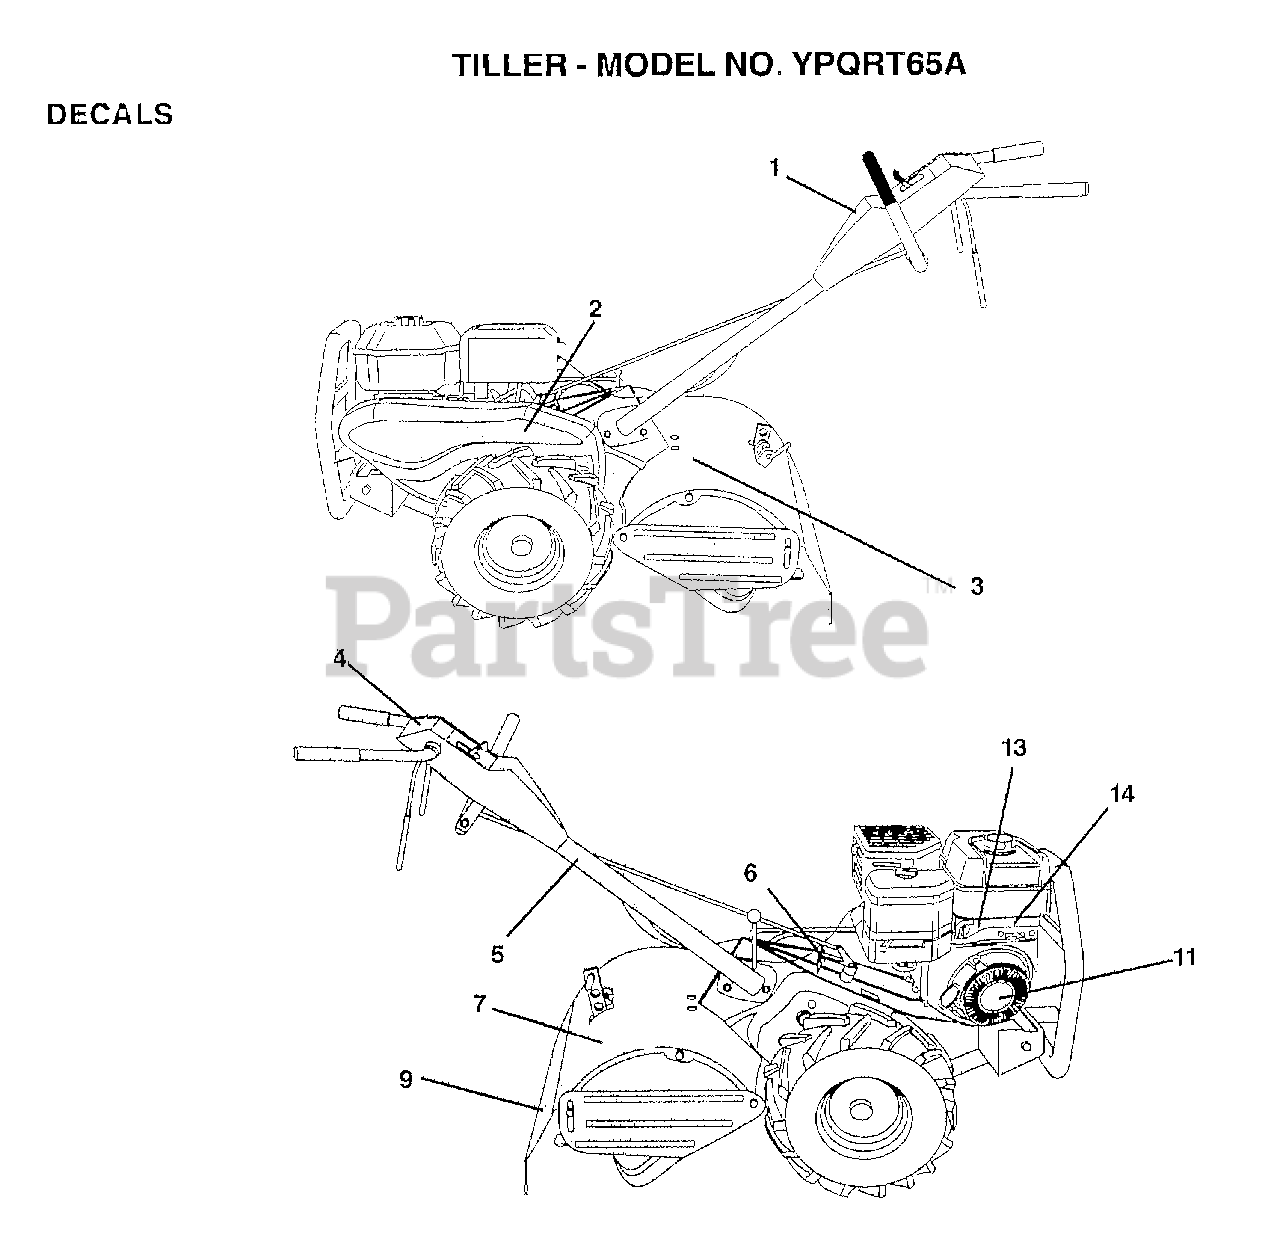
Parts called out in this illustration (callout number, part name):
1	DECAL PANEL CNTRL
2	DECAL, LOGO BELT GUARD
3	DECAL SHIELD TINE
4	DECAL.INSTRUCTION
5	DECAL TI
6	DECAL CRT
7	DECAL.CAUTION
13	DECAL, CHOKE
